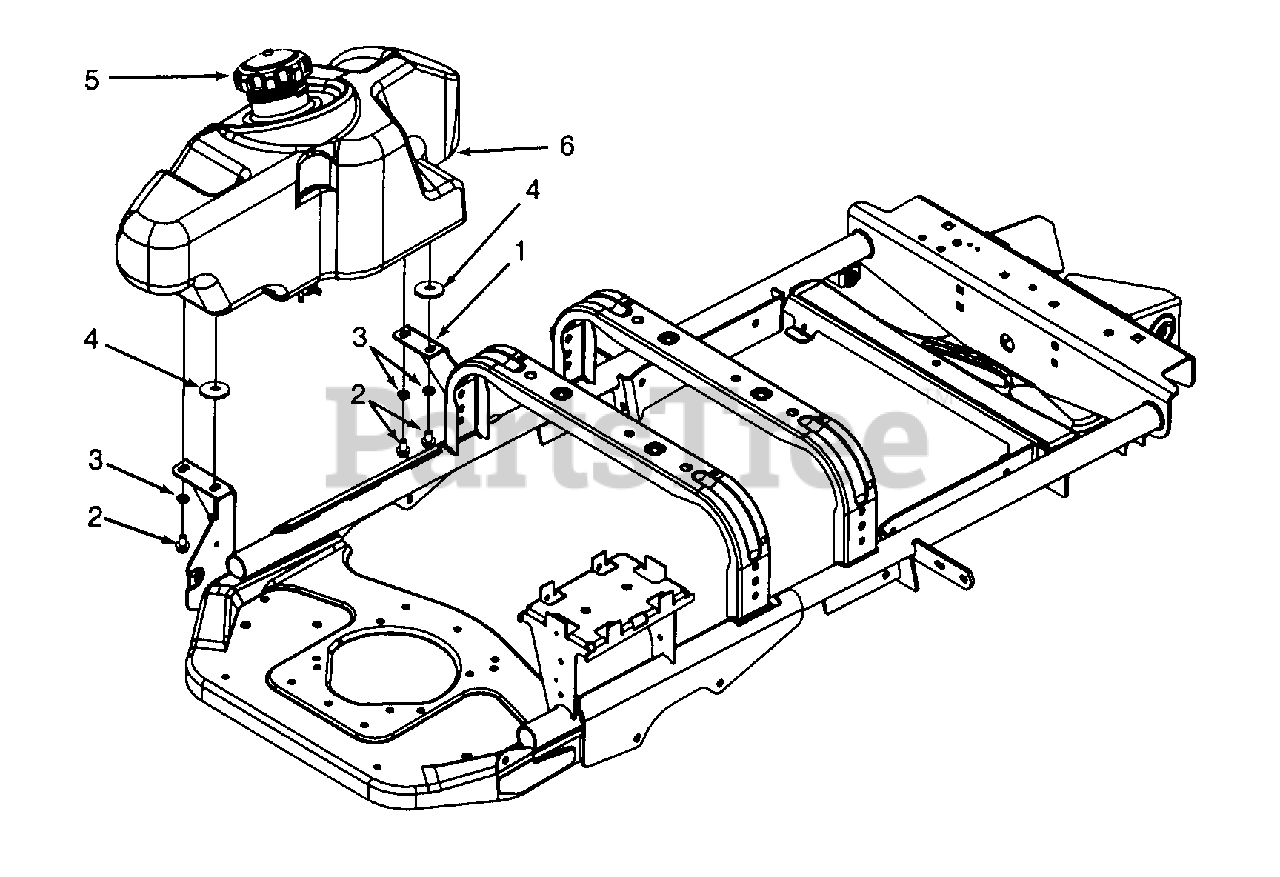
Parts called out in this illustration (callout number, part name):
3	Lock Washer 3/8
4	Flat Washer .390 ID x 1.5 OD
5	Fuel Cap
6	Fuel Tank
